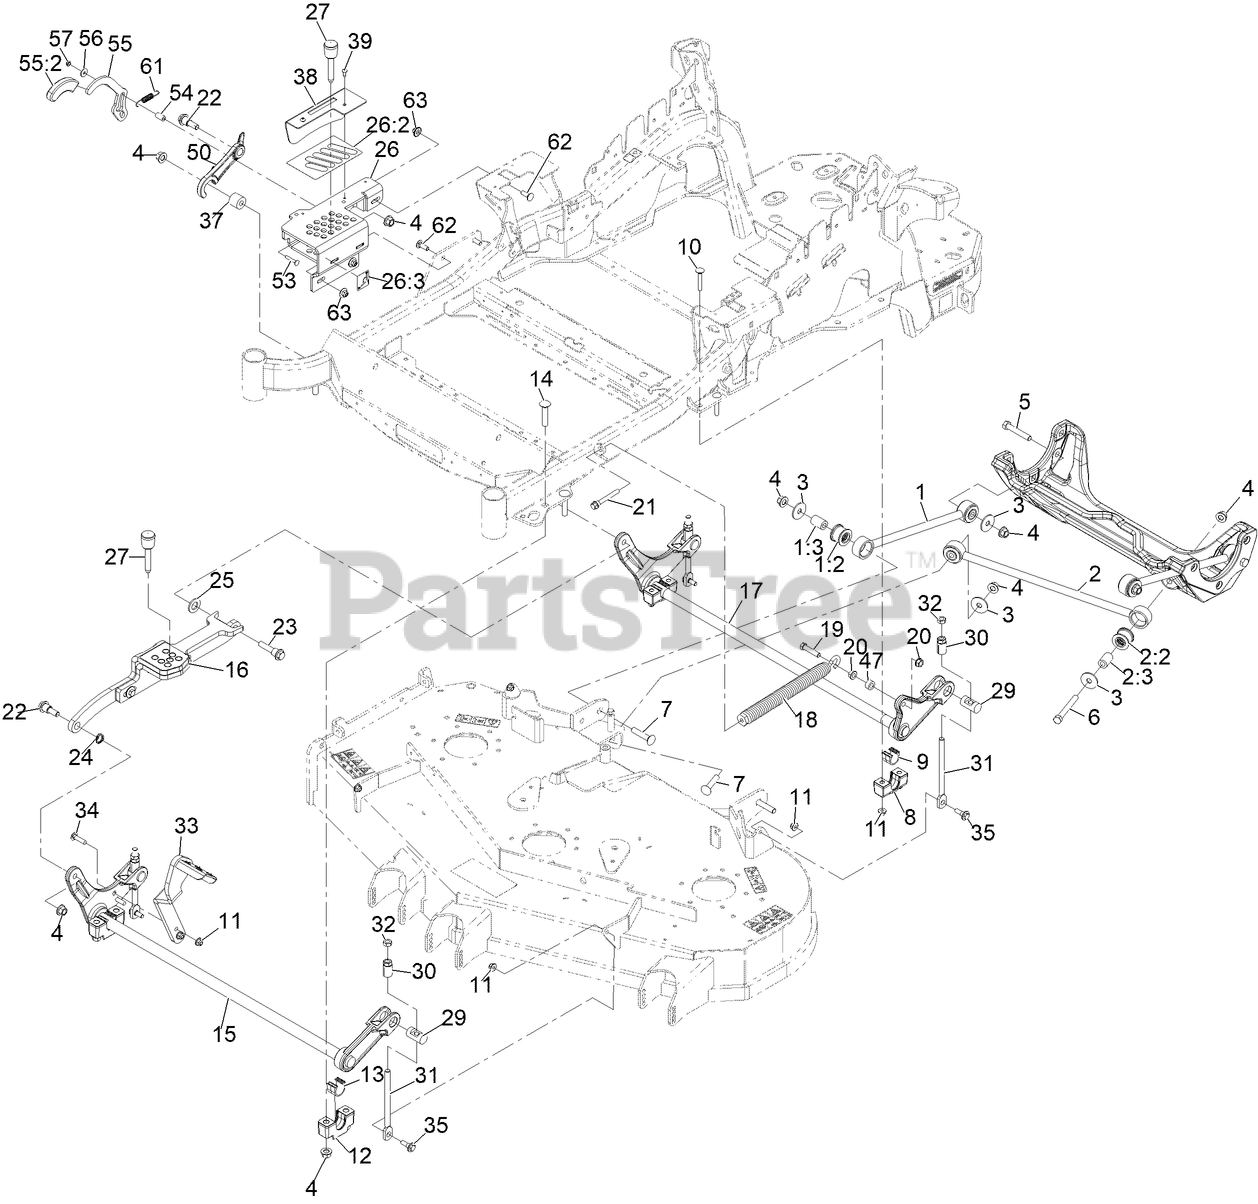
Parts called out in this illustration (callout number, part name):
1	DECK STRUT ASM
1:2	BUSHING-SUSPENSION, RUBBER
2	PANHARD ROD ASM
2:2	BUSHING-SUSPENSION, RUBBER
3	WASHER-THRUST
4	Nut-Lock 1/2-13
5	SCREW-HH
6	SCREW-HH
7	SCREW-CARR
8	SUPPORT-CROSS SHAFT, BEARING REAR
9	BEARING-CROSS SHAFT, REAR
10	Bolt-Carriage 3/8-16 X 2 1/4
11	NUT-HF, NI
12	SUPPORT-CROSS SHAFT, BEARING
13	BEARING-CROSS SHAFT, FRON
14	Bolt-Carriage 1/2-13 X 2 1/2 Spl Neck
15	Shaft- Deck Lift Front [black]
16	LINK-LIFT, DECK
17	Shaft- Deck Lift Rear [black]
18	SPRING-EXTENSION
19	SCREW-HH
21	BOLT-SHOULDER
22	SCREW-SHOULDER, HHF 1/2-13 X 1.12
23	SCREW-HHF, SHOULDER
24	WASHER-WAVE
25	WASHER-FLAT
26	ASM-HOC Box W/ Decals
26:2	Decal-HOC
26:3	DECAL-PARK BRAKE, CE
27	ASM- HOC PIN
29	TRUNNION
30	ADJUSTER-LIFT, DECK
31	LINK-ADJUSTER, DECK LIFT
32	NUT-JAM
33	LEVER-FOOT
34	SCREW-CARR
35	SCREW-SHOULDER, HHF
37	Bushing- Link
38	COVER-TRANSPORT LOCK
39	SCREW-TPH THD FORM
50	Latch-Transport, HOC
53	SCREW-CARR
54	Spacer- 0.50" OD
55	ASM-TRANSPORT LOCK LEVER W/ GRIP
55:2	GRIP-HANDLE, STEERING
57	NUT-LOCK, NI
61	Spring- Extension
62	Bolt-Carriage 3/8-16 X 1 1/4
63	Nut-Nyloc 3/8-16 Flg
